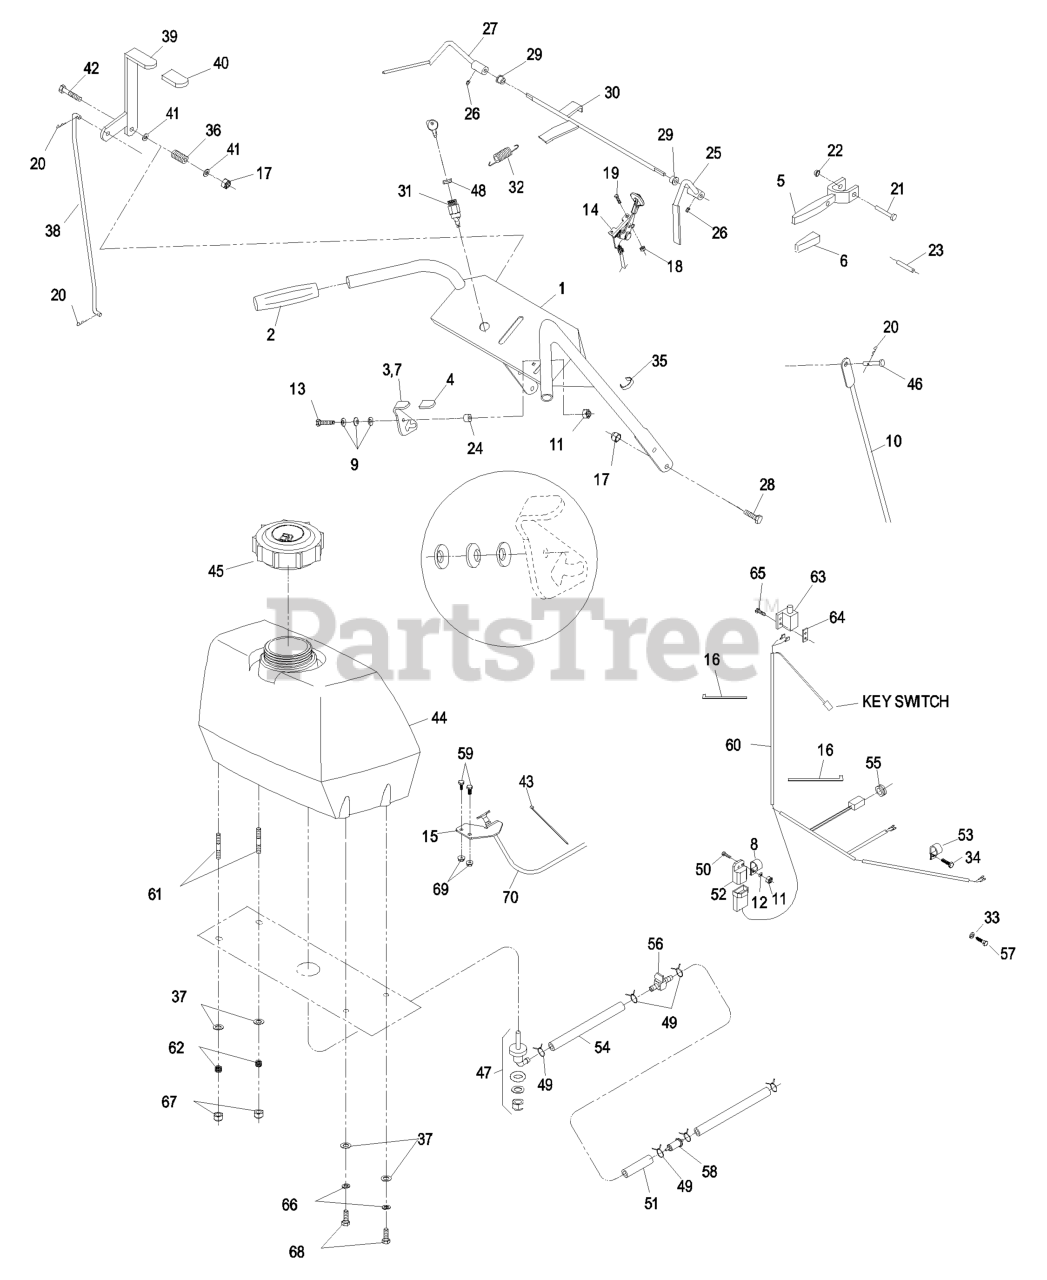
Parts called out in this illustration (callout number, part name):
1	KIT,HANDLE W/DECALS METRO
4	GRIP-LATCH
5	DRIVE LEVER ASM
6	GRIP-LEVER, DRIVE
8	CLIP-LOOM
9	WASHER-SPRING
10	LINKAGE-WHEEL, DRIVE
11	NUT-LOCK, NI
12	WASHER-FLAT
13	SCREW-HH
14	CONTROL-THROTTLE
15	BRACKET-CABLE, CHOKE
16	TIE-CABLE
17	NUT-LOCK, NI
18	NUT-LOCK, NI
19	BOLT-CARR
20	PIN-COTTER
21	PIN-LEVER, DRIVE
22	NUT-PUSH
23	PIN-ROLL
25	LEVER-RH
26	SCREW-SET
27	LEVER-LH
28	SCREW-HH
29	BUSHING-NYLON
30	WLD,ROD OPC
31	SWITCH & KEY (INCLUDES NU
32	SPRING-EXTENSION
33	WASHER-LOCK
34	SCREW-HH
35	CLIP-CABLE
36	SPRING-COMPRESSION
37	WASHER-PLAIN
38	LINKAGE-BLADE, UPPER
40	GRIP-LEVER
41	WASHER-FLAT
42	SCREW-HH
43	TIE-PLASTIC
44	ASM,FUEL TANK W/B
45	CAP-FUEL, GAS
46	PIN-CLEVIS
47	FITTING-FUEL, BULKHEAD
48	NUT-SWITCH, IGNITION
50	SCREW-HH
51	HOSE-FUEL
52	MODULE-INTERLOCK
53	CLIP-LOOM
54	HOSE-FUEL
55	GROMMET
56	VALVE-FUEL
57	SCREW-HH
58	Kawasaki Pn 41019-1055 W/6" Fuel Line
59	SCREW-HH
60	HARNESS-WIRING
61	STUD
62	SPRING-TANK, FUEL
63	SWITCH-OPEN, NORMALLY
64	PLATE-TAPPED
65	SCREW-PPH
66	WASHER-LOCK
67	NUT-LOCK, NI
68	SCREW-HH
70	CABLE-CHOKE
